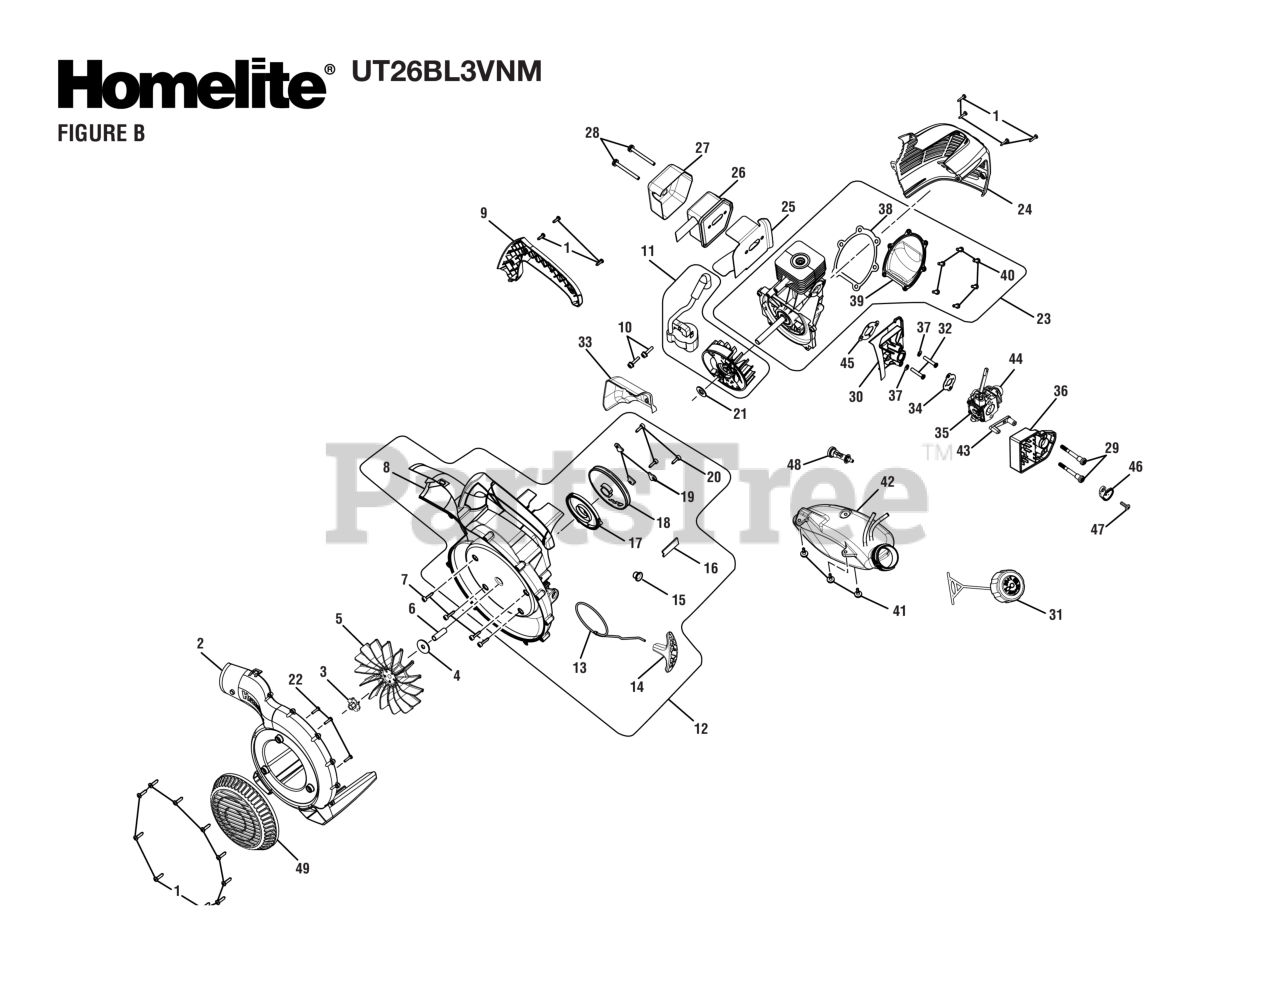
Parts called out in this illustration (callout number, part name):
1	Screw (M4 x 18 mm, T20 Torx Pan Hd. S.T.)
2	Outer Volute w/Label
3	Lock Nut (3/8 in.)
4	Washer (ID9.8 x OD34.27 x 2.28t)
7	Screw w/Washer (M4 x 16 mm, T25 Torx Truss Hd.)
8	Inner Volute w/Eyelet and Label
9	Handle Cover
10	Screw w/Washer (M4 x 19 mm, T20 Torx Pan Hd. S.T.)
11	Ignition Module and Flywheel Kit
12	Lower Housing w/Starter and Label Assembly
13	Starter Rope (42 in.)
14	Pulley Handle
17	Spring & Container Assembly
18	Starter Pulley
19	Pulley Retainer
20	Screw (M4 x 14 mm, T20 Torx Truss Hd T.F.)
21	Washer (ID9.70 x OD20 x 1.59t)
22	Screws (10-14 x 3/4 in., T25 Torx Pan Hd. T.F.)
23	Short Block Assembly
24	Engine Cover w/Label
25	Muffler Gasket
26	Muffler Assembly
27	Muffler Heat Shield
28	Screw w/Washers (10-24 x 2-1/8 in., T25 Torx Truss Hd.)
29	Shoulder Bolt (M5 x 46.5 mm)
31	Fuel Cap Assembly (Inc. Tether)
32	Screw (M5 x 25 mm, T20 Torx Hd.)
33	Baffle Plate
34	Heat Dam Gasket
35	Carburetor
36	Air Box Base
38	Crankcase Cover Gasket
39	Crankcase Cover
40	Screw (M4 x 12 mm, T20 Torx Hd.)
41	Shoulder Screw w/Washer (M4 x 14 mm, T25 Torx Truss Hd.)
42	Fuel Tank Assembly (Inc. Fuel Lines)
43	Choke Lever
44	Primer Bulb (Ruixing)
45	Inner Heat Dam Gasket
46	Choke Cover
47	Screw (M4 x 12 mm, Slotted Recessed Pan Hd.)
48	Fuel Filter
49	Blower Door
